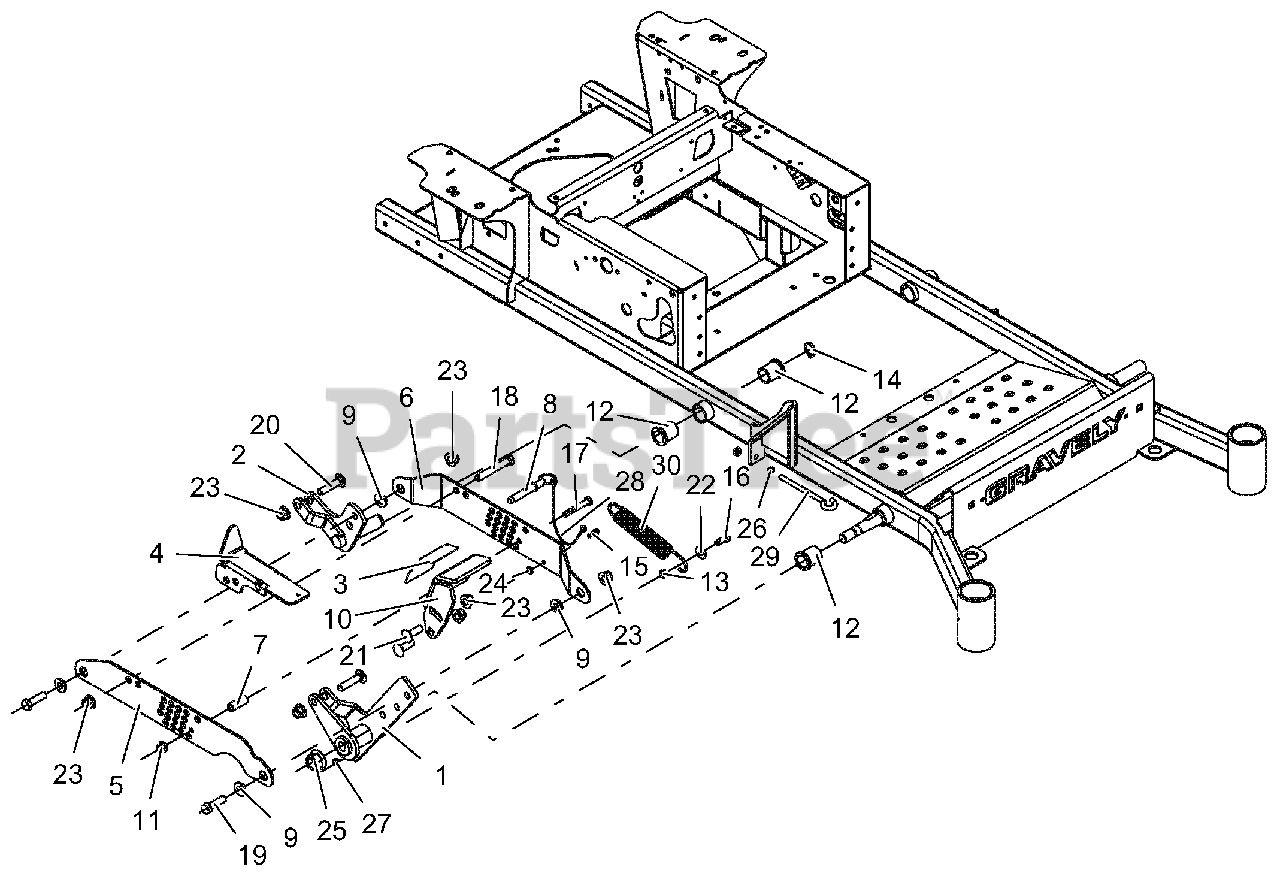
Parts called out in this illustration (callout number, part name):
1	WLDMT, TAPERED LIFT ARM FRONT LH-BLACK
2	WLDMT, RH REAR DECK LIFT
3	GRIP, PEDAL 1.50 X 3.00
4	WLDMT, MECHANICAL LOCK-UP-BLACK
5	BRKT, RH OUTBOARD LIFT/CUT HEIGHT-BLACK
6	BRKT, RH INBOARD LIFT/CUT HEIGHT-BLACK
7	SPACER, .375 X .625 X 1.54
8	PIN, .50 X 2.00 USABLE LG BALL
9	BSHG, FLANGE .515X.750X.31X1.12
10	PEDAL, ADJUSTABLE FOOT LIFT-BLACK
11	NUT-LK-NYL-FLG .38-16 YWZC
12	BSHG-FLG 1.00X1.25X1.5X1.5
13	BSHG, SLV .377X.624X.235
14	RG-RTNG-EXT 1.00X.078
15	BLT-HEX .25-20X.75 GR5 YWZC
16	BLT-HEX .38-16X1.00 GR5 YWZC
17	BLT-HEX .38-16X2.50 GR5 YWZC
18	BLT-HEX .50-13X3.25 GR5 YWZC
19	BLT-HEX .50-13X1.75 GR5 YWZC
20	BLT-RDHDSQNK .50-13X2.25 G5 Y
21	BLT-RDHDSQNK .50-13X1.50 G5 YWZC
22	WSHR-FL-STL.438X1.00X.083 YWZC
23	NUT-LK-NYL-FLG .50-13 YWZC
24	NUT-LK-NYL-FLG .25-20 YWZC
25	NUT-LK-NYL-FLG .75-10 YWZC
26	NUT, JAM .375-16 YWZC
27	@NUT-LK-CTR-JAM .375-16 YWZC
28	LANYARD, 12"
29	BOLT, EYE .38-16X6.00 .62 DIA
30	SPRG, EXTENSION
